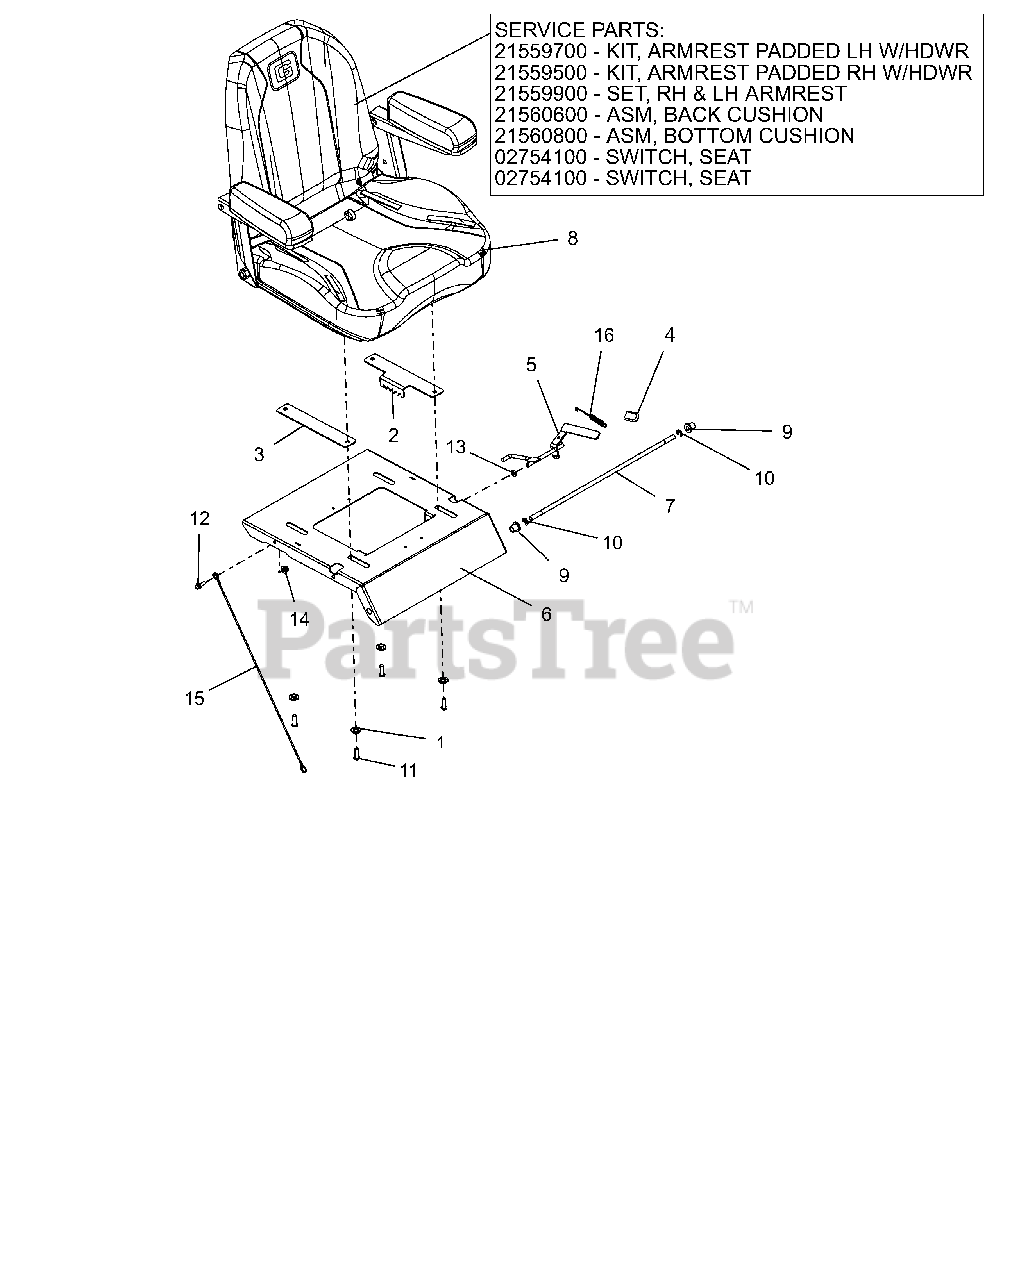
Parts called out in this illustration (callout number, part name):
1	BSHG, FLG .325X.499X.26X.88
2	PLATE, ADJUSTABLE SEAT TRACK
3	PLATE, ADJUSTABLE SEAT SLIDE
4	GRIP, SEAT LEVER, GREY
5	WLDMT, ADJUSTABLE SEAT LATCH
6	PLATE, SEAT
7	ROD, SEAT PIVOT
8	SEAT, ZTXL 2017
8	PAD, LH ARMREST
8	PAD, RH ARMREST
8	SET, RH & LH ARMREST ASM
8	ASM, BACK CUSHION-GRAVELY XL
8	ASM,BOTTOM CUSHION-GRAVELY XL
8	SWITCH- SNAP MTG N.O.
9	BSHG-FLG .38X.580X.667X.750
10	RG-RTNG-EXT .375X.035 TYP E
11	SCR-SKH .31-18X1.0 BTNHD YWZC
12	BLT,HEX-FLG .25-20X.75 G5 BFP
13	NUT-PUSH .312
14	@NUT-LK-NYL-FLG .31-18 YWZC
15	LANYARD, SEAT CABLE .093X19.5
16	SG-TENS .043X.44X3.31 WLD 5.8
